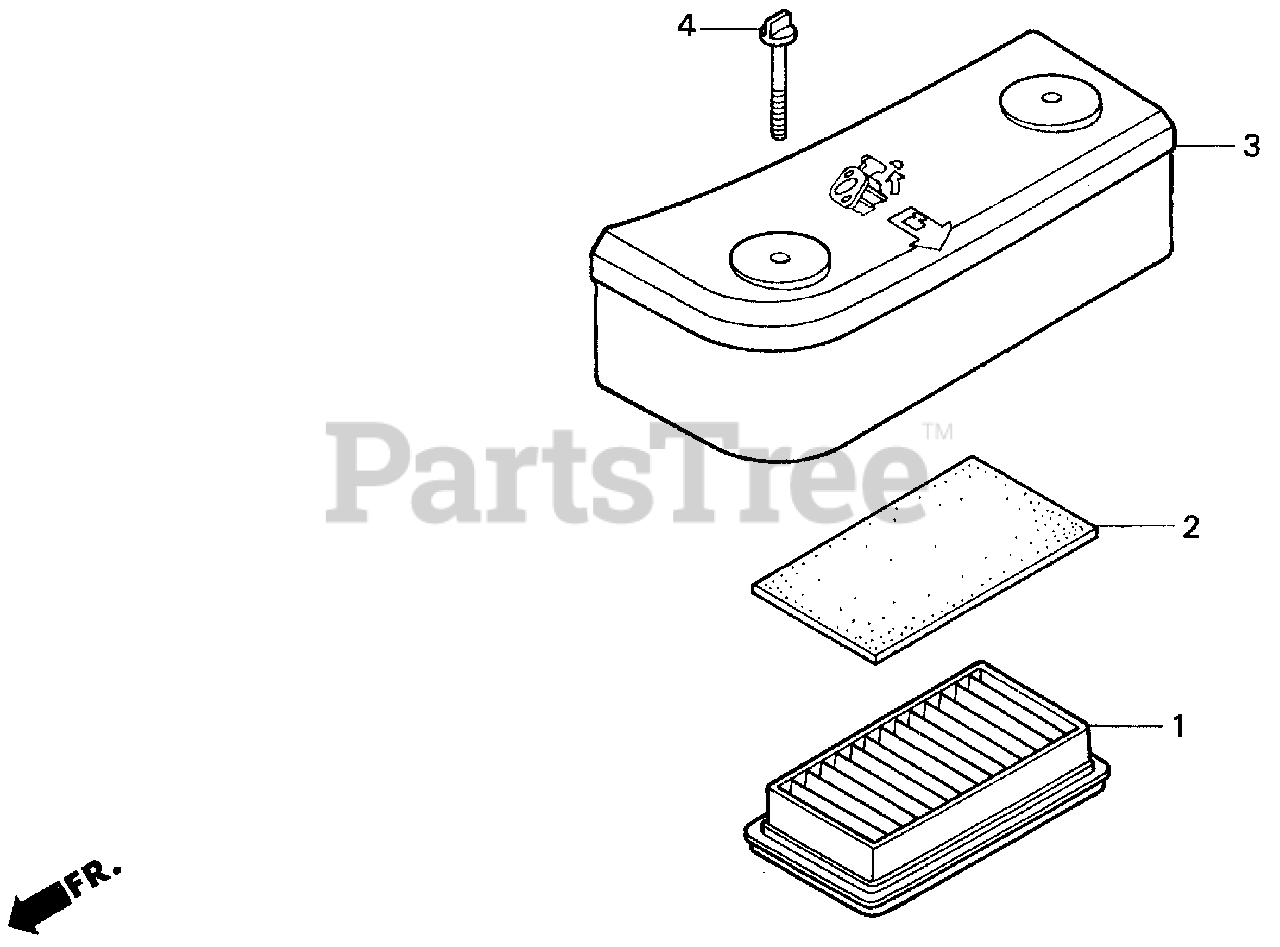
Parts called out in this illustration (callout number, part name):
1	ELEMENT, AIR CLEANER
2	FILTER (OUTER)
3	COVER, AIR CLEANER *NH1* (TEXTURED) (BLACK)
4	BOLT, AIR CLEANER (6MM)
